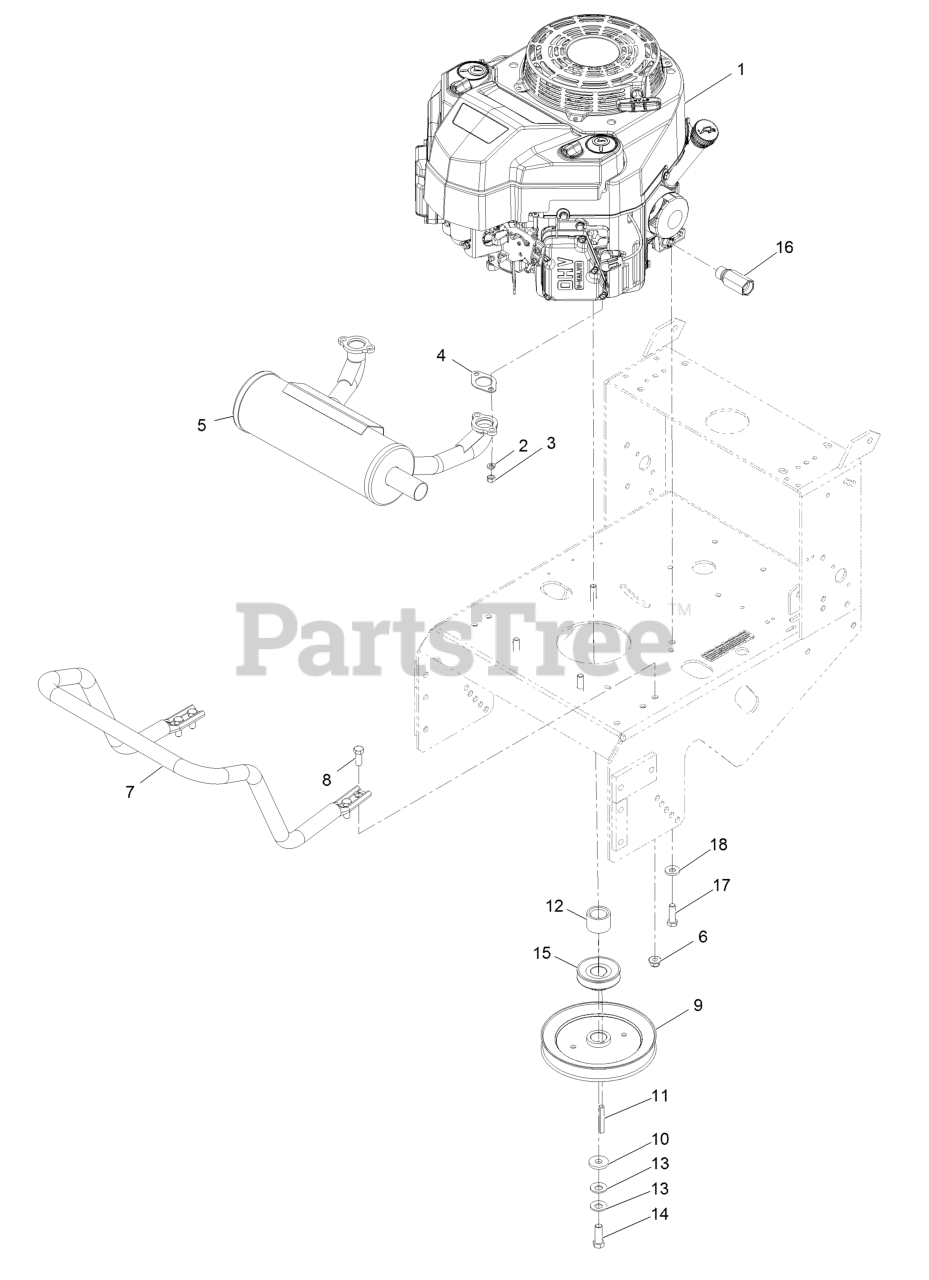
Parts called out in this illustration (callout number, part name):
1	Engine-Kawasaki
2	Washer-Spring Lock M8
4	Gasket-Exhaust
5	Muffler-Horizontal
6	Nut-Nyloc 3/8-16 Flg
7	Guard-Muffler
8	Screw-HH 3/8-16 X 1
9	Sheave
12	Spacer-Clutch
13	Washer-Spring Disc 7/16
14	Screw-HH
15	Sheave-Transmission
16	Adapter
17	Screw-HH 3/8-16 X 1 1/4
18	Washer-Spring Disc 3/8
